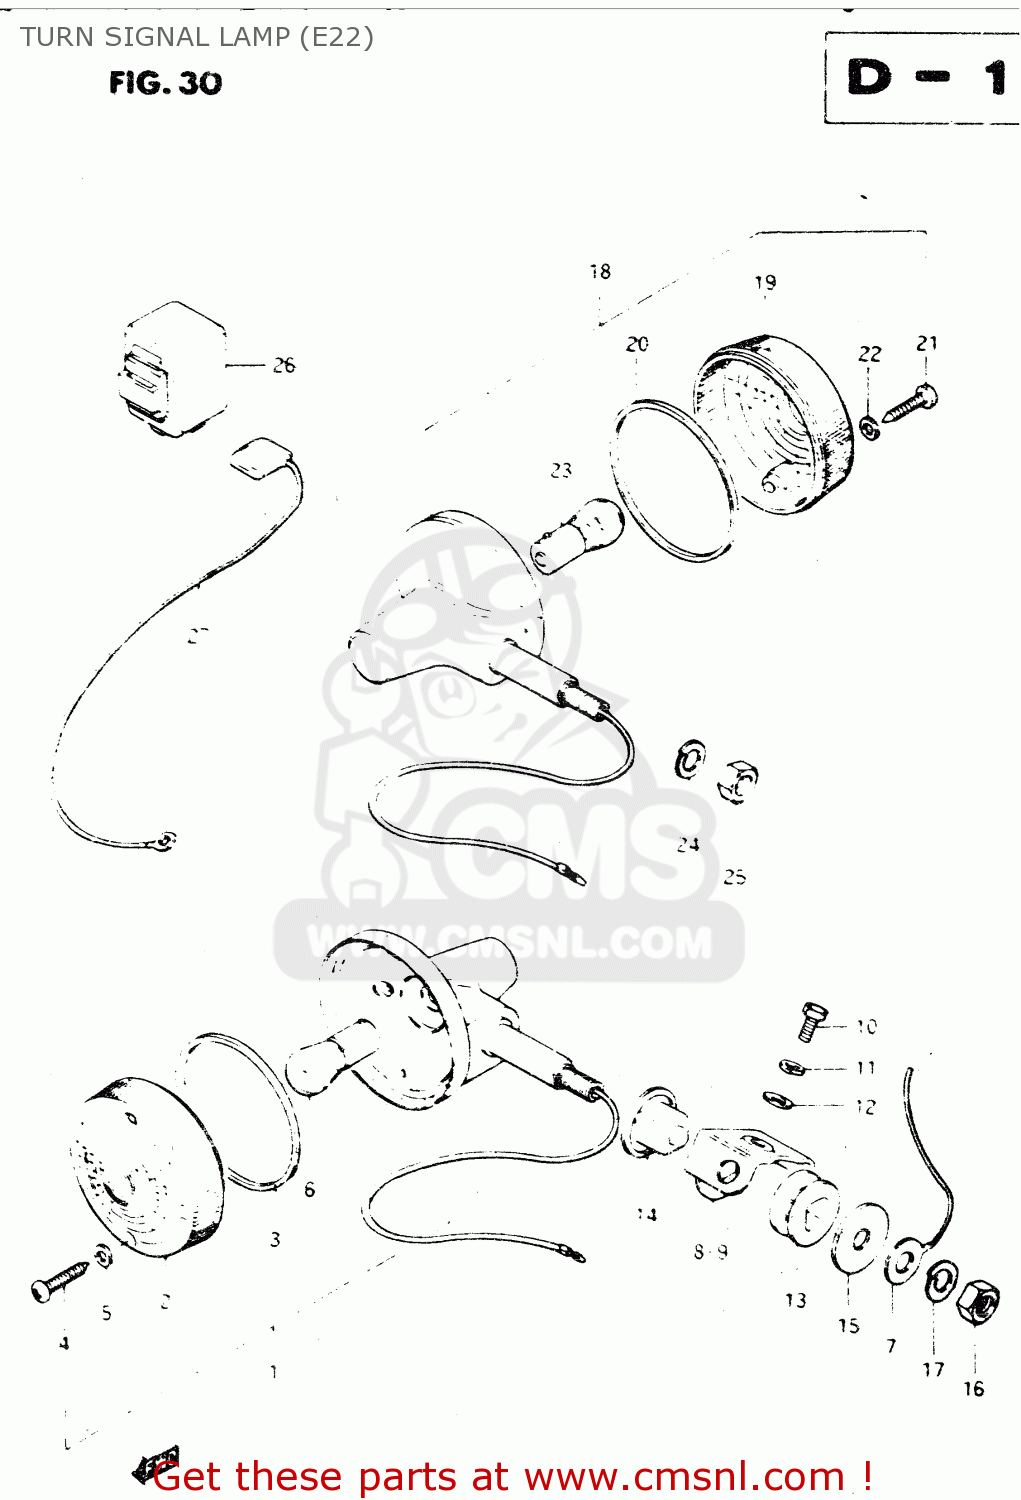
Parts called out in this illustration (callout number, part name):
1	LAMP, FRONT TURN SIGNAL
2	LENS
3	GASKET (NAS)
4	SCREW
5	GASKET (NAS)
6	BULB(12V21W)
7	LEAD WIRE,EARTH
8	BRACKET,TURNSIGNAL LAMP,R
9	BRACKET,TURNSIGNAL LAMP,L
10	BOLT
11	LOCK WASHER
12	WASHER
13	CUSHION
14	SPACER
15	WASHER (10.5X30X2.3)
16	NUT
17	LOCK WASHER
18	LAMP, REAR TURN SIGNAL
19	LENS,TURN SIGN
20	GASKET (NAS)
21	SCREW
22	GASKET (NAS)
23	BULB(12V21W)
24	LOCK WASHER
25	NUT
26	RELAY, TURN SIGNAL
27	LEAD WIRE
